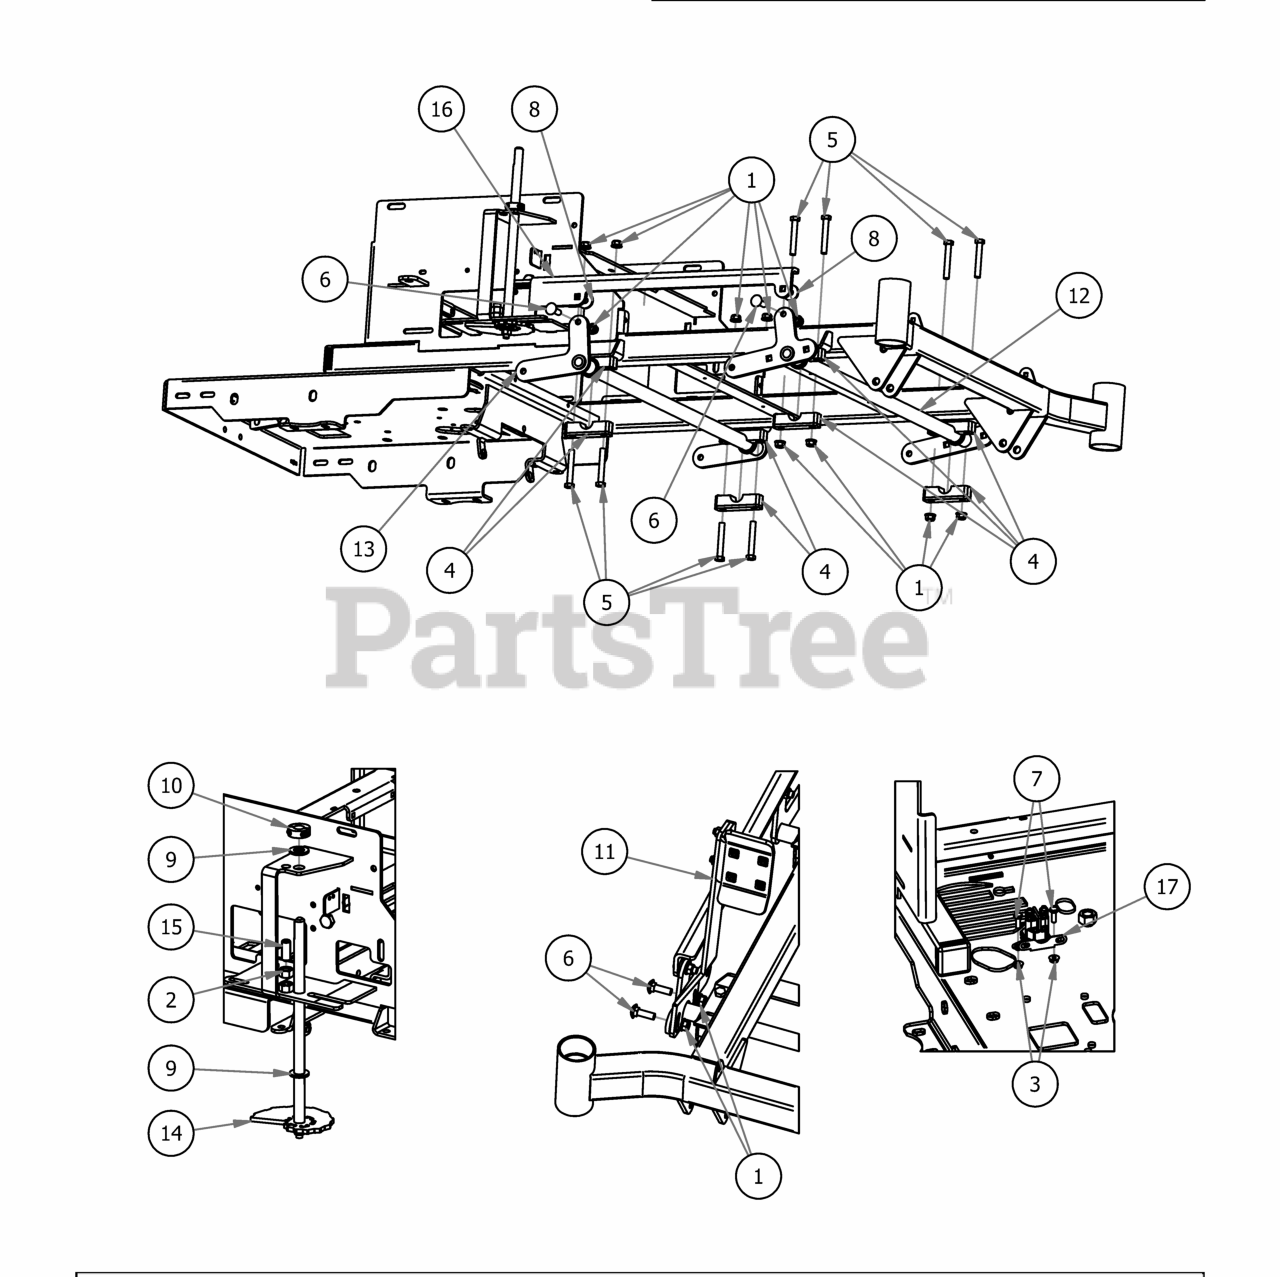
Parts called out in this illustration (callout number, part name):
1	3/8" Nylock Flange Nut
2	1/2" Hex Nut
3	1/4-20 Hex Flange Nuts Zinc w/Serrations
4	Pillow Block Kit
5	3/8-16 x 2 1/2" Hex Bolt
6	3/8" x 1 1/4" Carriage Bolt
7	1/4" x 3/4" Hex Bolt
8	.390 ID Plastic Washer
9	.630 ID x 1.122 OD x .142 THK Plastic Washer
10	5/8" Split Collar
11	Foot Pedal Assembly
12	Actuator Bar Front- 2017 MZ/ZT
13	Actuator Bar Rear- 2017 MZ/ZT
14	Deck Height Dial Rod Assembly
15	Dial Rod Plunger
16	2017 MZ/ZT Actuator Linkage
